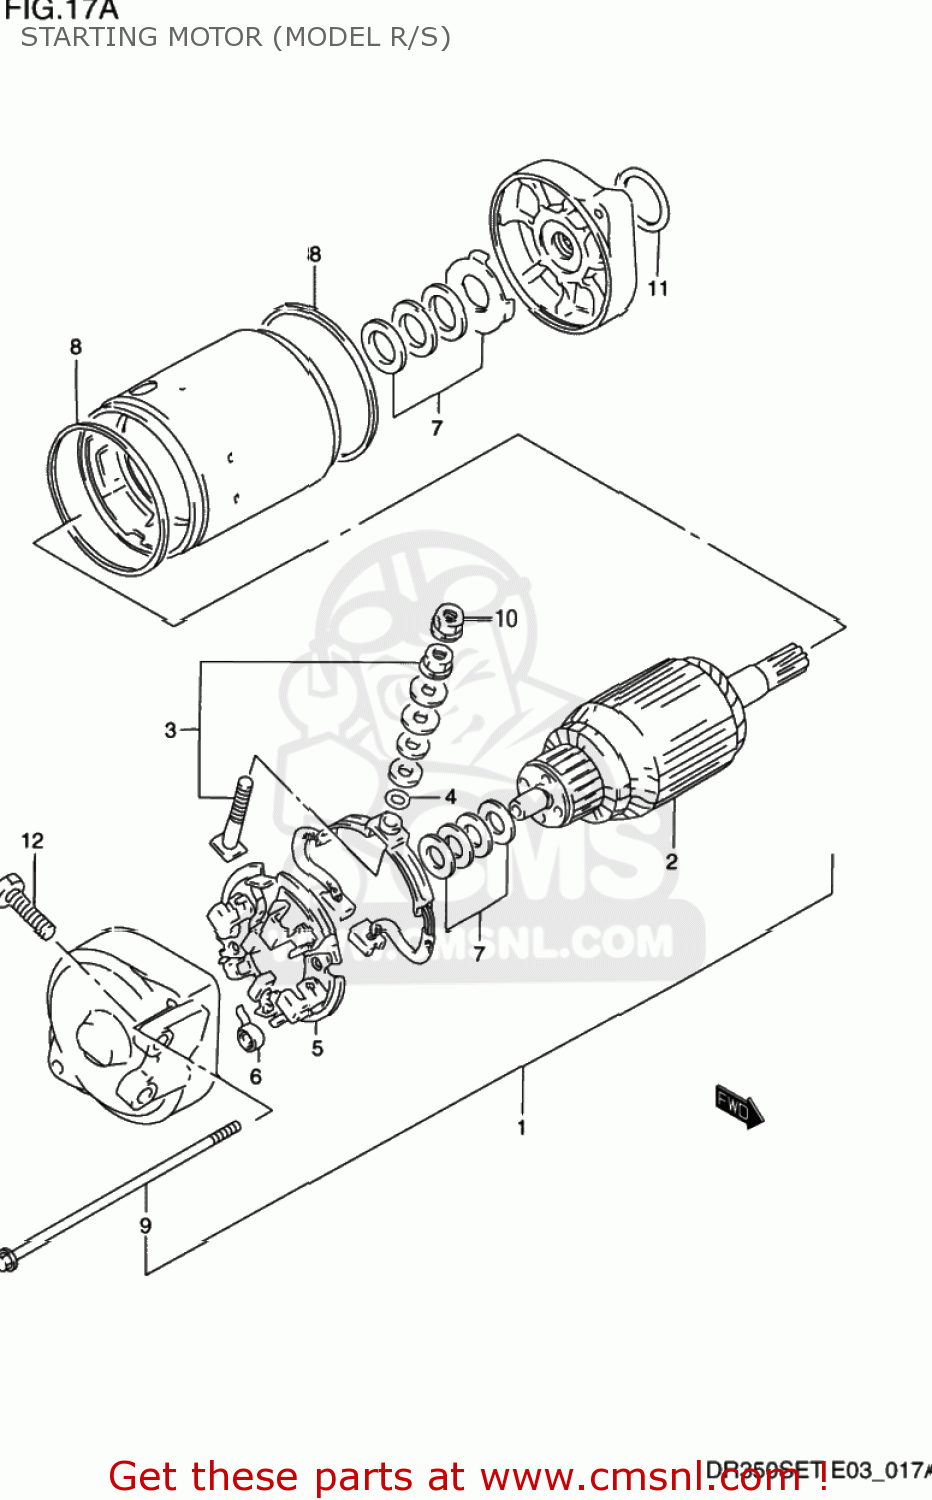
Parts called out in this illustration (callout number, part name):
1	MOTOR ASSY,STARTING
2	ARMATURE
3	TERMINAL SET,BRUSH
4	O RING
5	HOLDER SET,BRUSH
6	SPRING,BRUSH
7	SHIM SET,STARTING MOTOR
8	O RING
9	BOLT
10	NUT
11	O RING(D:3,ID:24.5)
12	BOLT,CRKCASE,R
